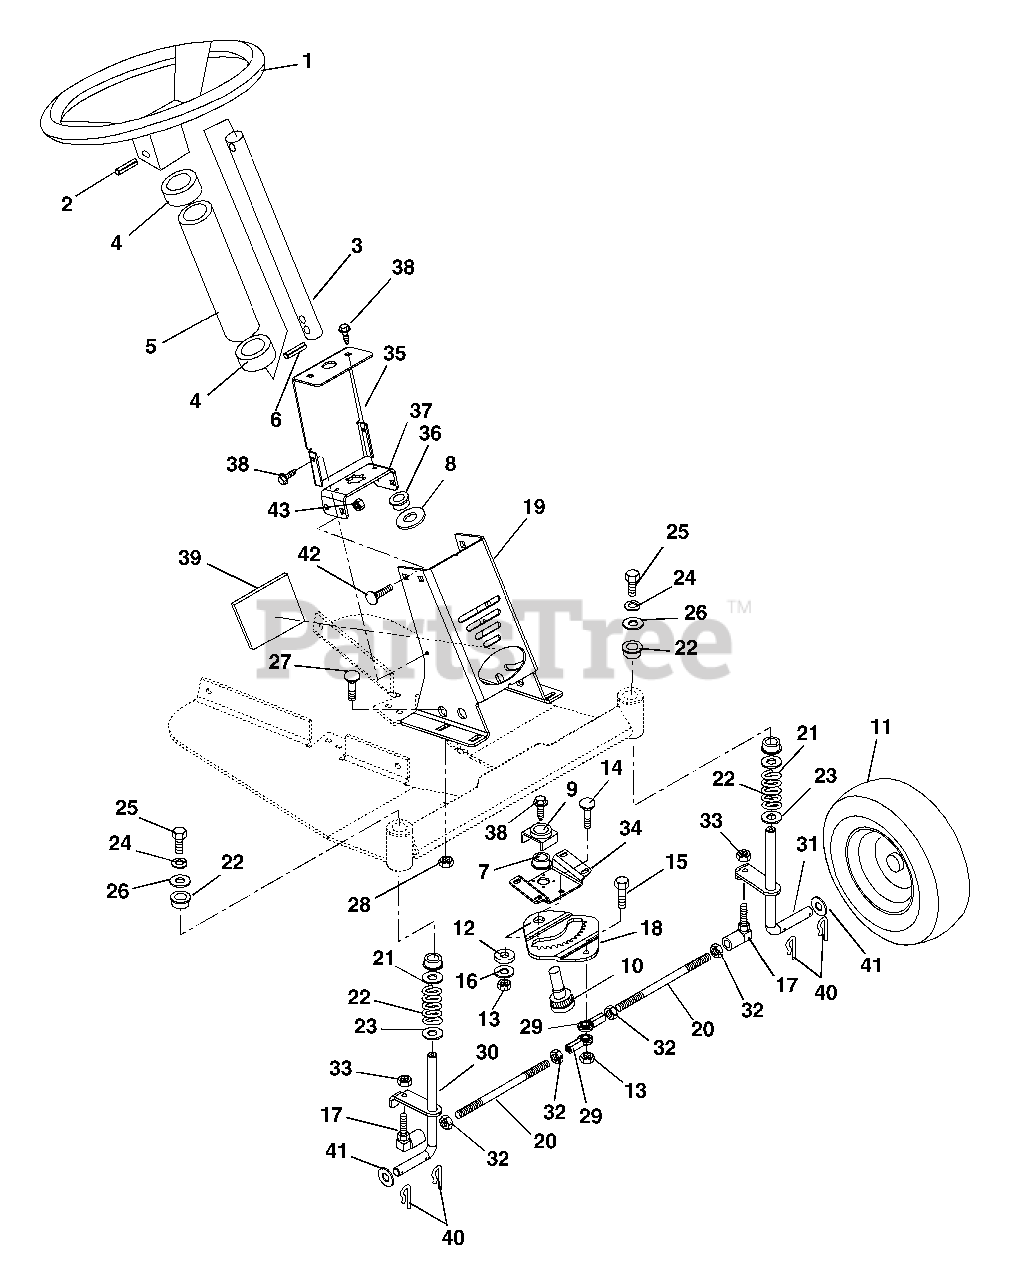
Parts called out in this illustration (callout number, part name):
1	Steering Wheel 13 Inch
2	Pin, Roll .25 x 1.75
3	Steering Shaft
6	Pin, Roll .188 x .75
7	Bushing, Flange .625 x 1.156 x .375
8	Washer, Hardened Steel .515 x .97 x .062
9	Retaining Plate 1
10	Pinion
11	Tire/Wheel Assembly
11	Tire 4.10/3.50 - 4
11	Bushing, Flange .75 x 1.38 x .75 x 1.557
12	Spacer, Steering Gear
13	Nut, Locking Top Flange .38-16
14	Bolt, Round Head Square Neck .38-16 x 1.00 Grade 5
15	Bolt-Hex .38-16 x 1.75 Grade 5
16	Washer, Flat Steel .406 x 1.375 x .135
17	Ball Joint
18	Steering Gear
19	Box, Steering
20	Steering Link
21	Spring, Suspension
22	Bushing 1.00 x .75 x 1.00
23	Washer-Flat-Steel .70 x 1.47 x .134
24	Washer, Locking .31 x .078 Regular
25	Bolt, Hex .31-18 x .75 Grade 5
26	Washer, Flat Steel .406 x 1.375 x .135
27	Bolt, Round Head Square Neck .38-16 x .75 Grade 5
28	Nut, Locking Top Flange .38-16
29	Rod End, .38 Right Hand
30	Weldment, Spindle Right Hand
31	Weldment, Spindle Left Hand
32	Nut, Jam .375-24
33	Nut, Locking Nylon .375-24 With Insert
34	Steering Gear Support
35	Bracket, Steering Column
36	Bushing, Flange
37	Support, Steering Column
38	Screw, Tapping .312-18 x .50 Hex Washer Head
39	Cover, Light
40	Pin, Spring Clip
41	Washer, Flat Steel .755 x 1.375 x .062
42	Bolt-Round Head Square Neck .31-18 x .75 Grade 5
43	Nut-Locking-Nylon .312-18
